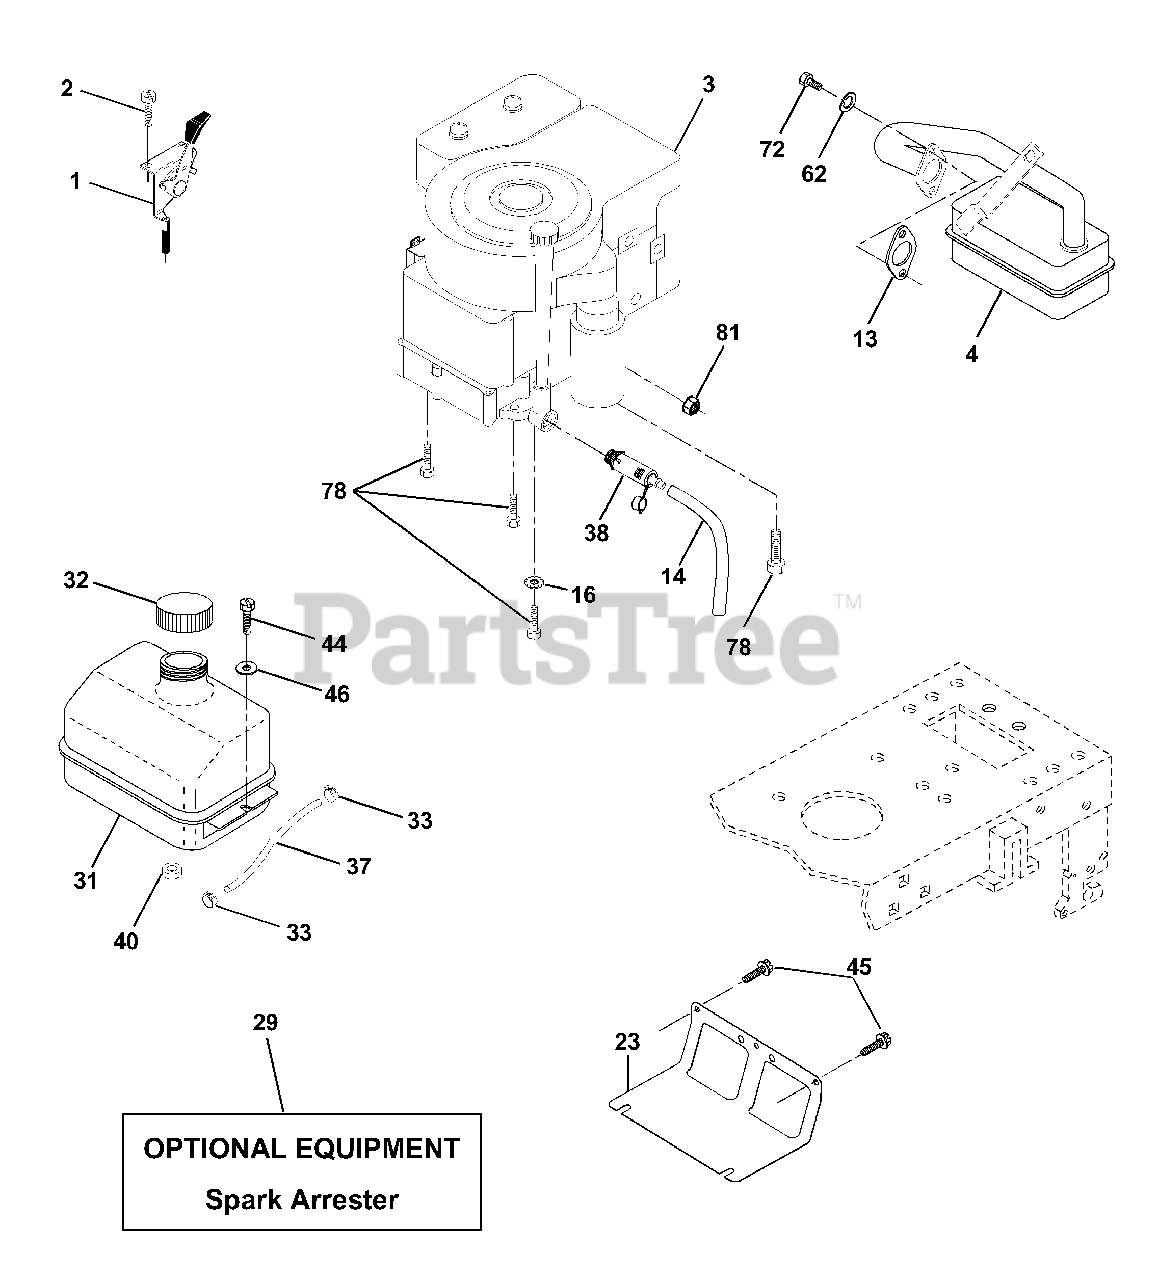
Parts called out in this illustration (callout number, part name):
1	Control Th/ch Flag
2	Screw Hex Thd Cut 1/4-20x5/8 T
4	Muffler LT B&S 12/12.5/13HP
13	Gasket Eng 1 313 Id Tin Plated
14	Tube Drain Oil Easy
16	Washer Lock Ext Tooth 3/8
23	Shield Brn/Dbr Guard
29	Kit Spark Arrestor (Flat Scrn)
31	Tank Fuel Front
32	Cap Asm Fuel W/sym Vented
33	Clamp Hose Black
37	Line Fuel 20"
38	Plug Drain Oil Easy
40	Bushing Snap Nyl Blk Fuel Line
44	Screw Hexwsh Thdrol 1/4-20 x 3/4
45	Screw Hexwsh Thdr 3/8-16 x 3/4
46	Washer 9/32 x 7/8 x 16 Ga
62	Washer Lock Hvy Hlcl Spr 5/16
72	Screw Hexhd Cap 5/16-18 x 3/4
78	Screw 3/8-16 x 1-1/4
81	Nut Keps Hex 1/4-20 Unc
